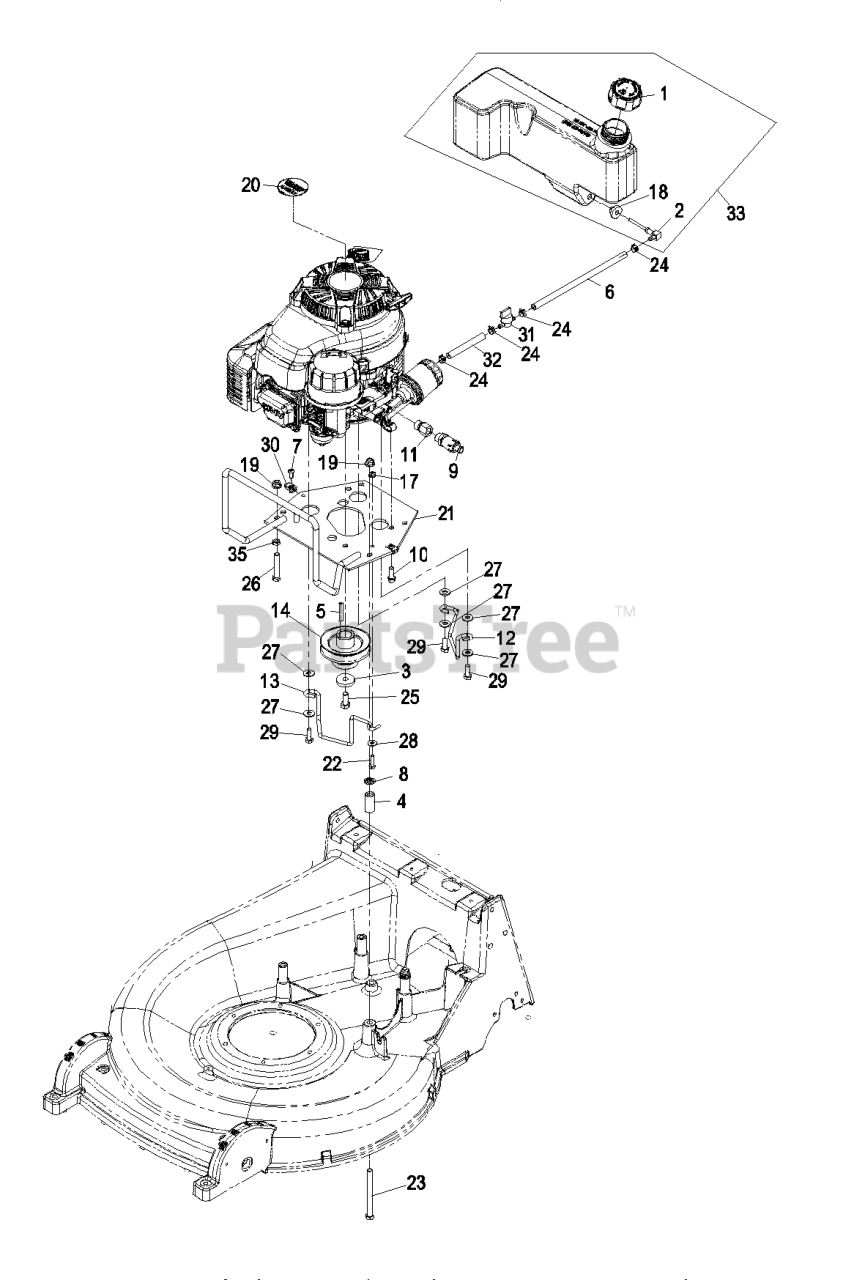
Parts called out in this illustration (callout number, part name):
1	CAP-FUEL
2	ELBOW-TANK, FUEL
3	WASHER-CLUTCH
5	KEY-SQUARE
6	HOSE-FUEL
8	RING-RETAINING
9	VALVE-DRAIN, OIL
10	SCREW-TAPTITE
11	ADAPTER
12	GUIDE-BELT, REAR
13	GUIDE-BELT, FRONT
14	SHEAVE-DRIVE
18	BUSHING
19	NUT-HF, NI
21	PLATE-ENGINE
22	SCREW-HH
23	SCREW-HH
24	CLAMP-HOSE
25	SCREW-HH
26	BOLT-CARR
27	WASHER-FLAT
28	WASHER-BELLEVILLE
29	SCREW-HH
30	Nut, Retainer-Panel 1/4-20
31	VALVE-FUEL
32	HOSE-FUEL
33	ASM,FUEL TANK M26 W/CAP
35	NUT-JAM
